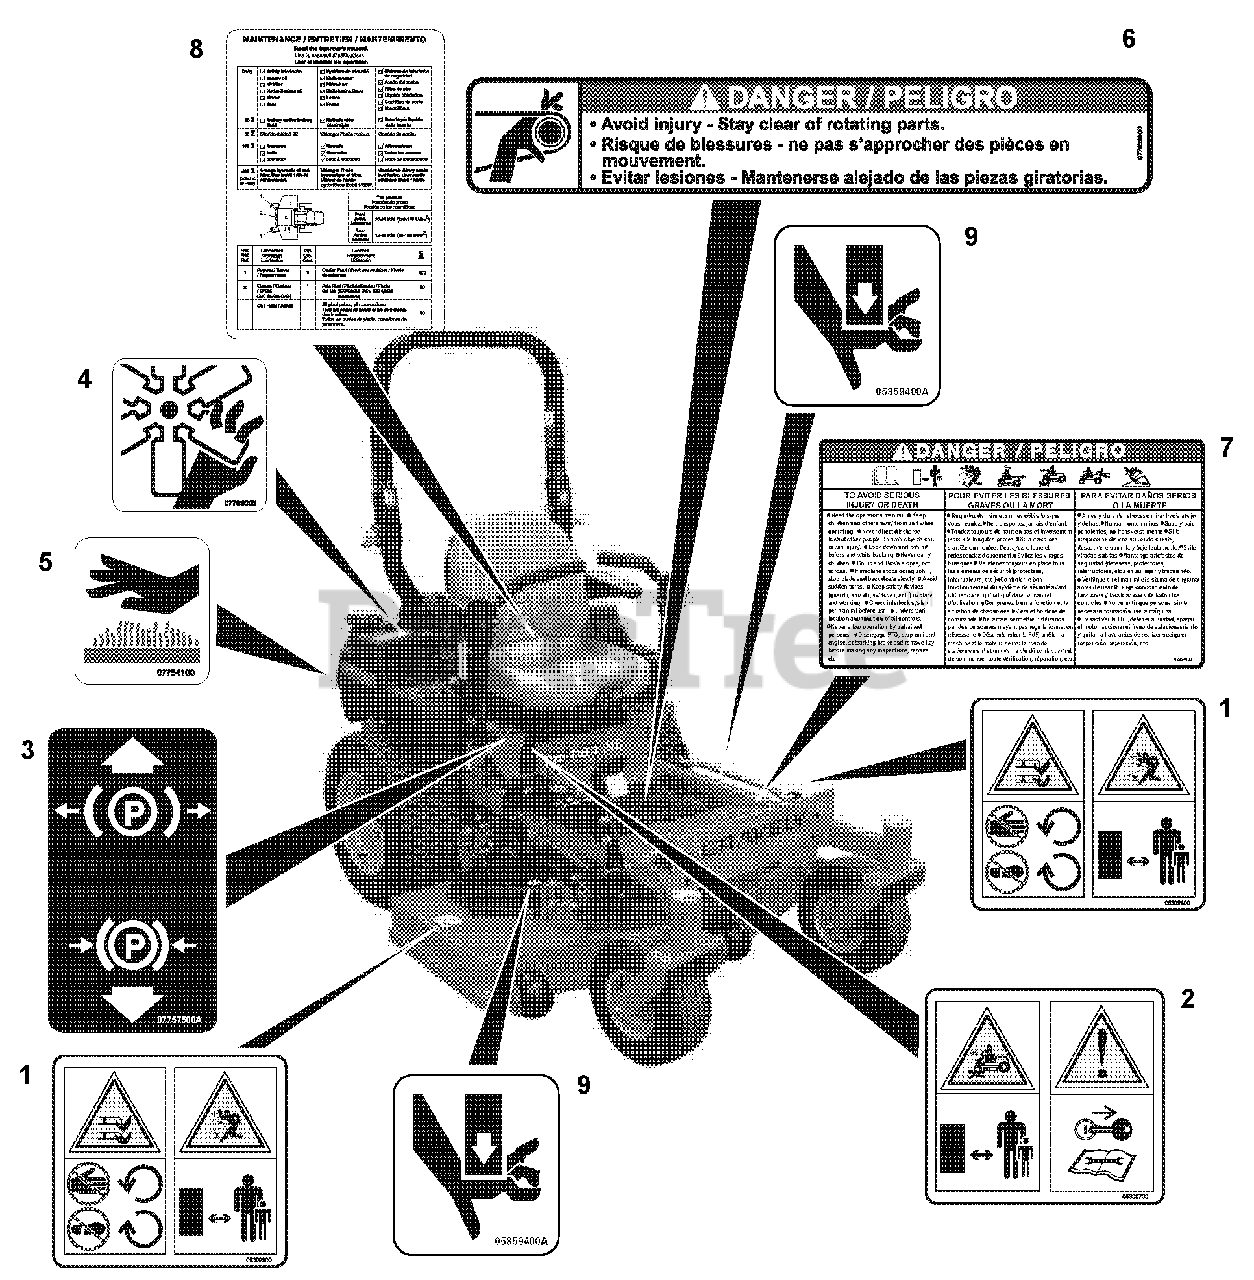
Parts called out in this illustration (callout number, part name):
1	Decal, CE Deck
2	Decal, CE Caution
3	Decal, Parking Brake Lever
4	Decal, Danger Fan
5	Decal, Hot Surface
6	Decal, Danger Rotating Parts
7	Decal, Danger-Bilingual
8	Decal, Maintenance Instructions
9	Decal, Pinch Point
